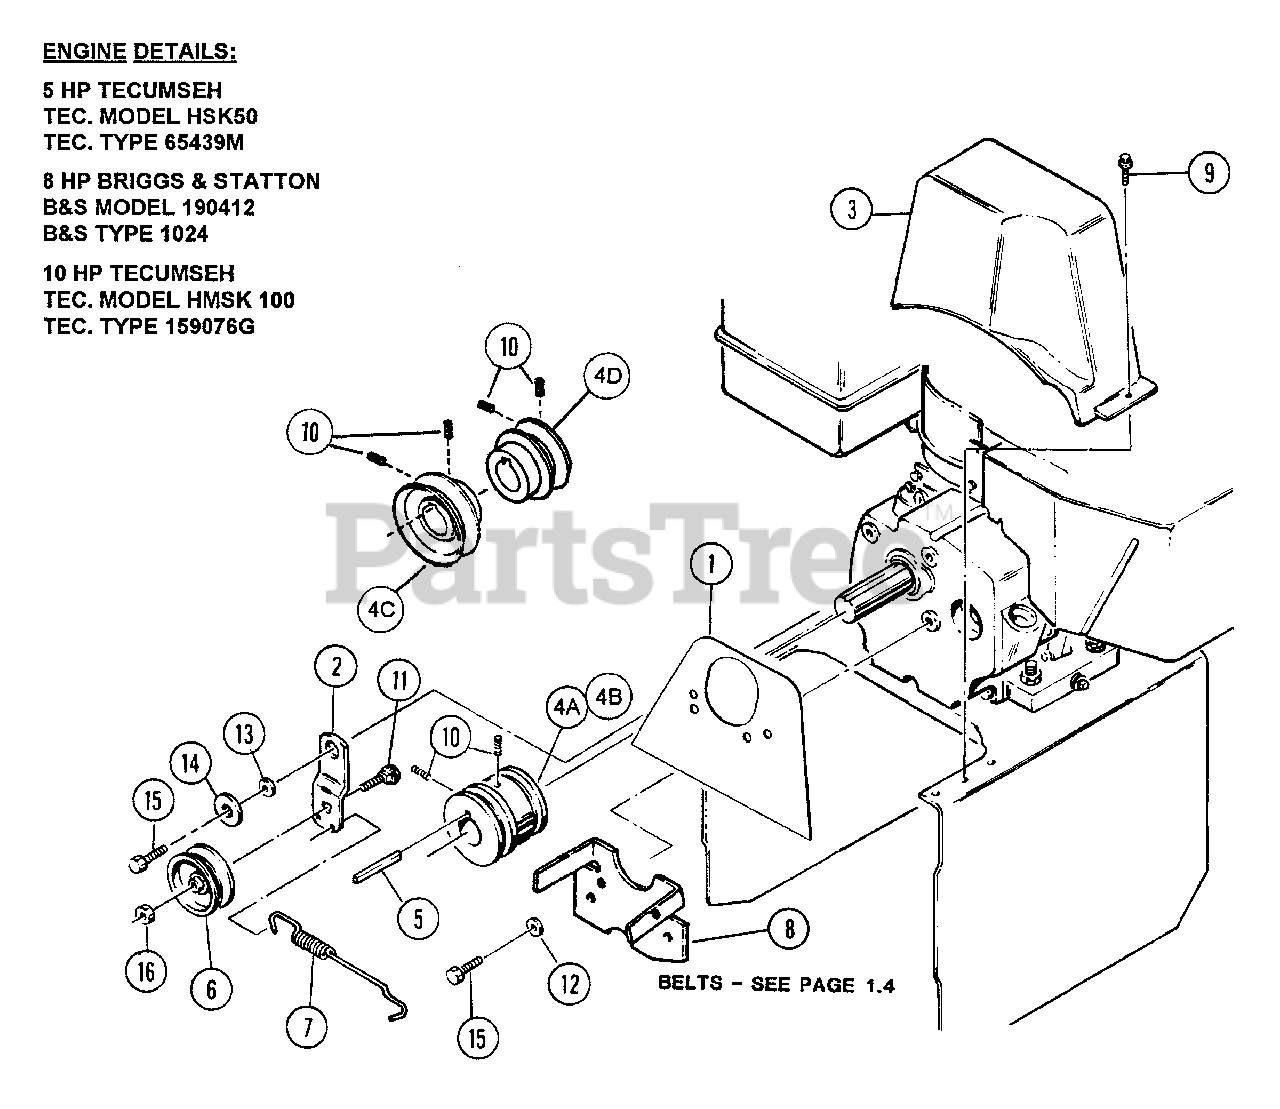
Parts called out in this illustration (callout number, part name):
1	GUARD, Engine
2	ARM, Idler
3	COVER, Belt
4A	PULLEY, Double 1x2.5, 2.75
4B	PULLEY, Double .75x2.5, 2.75
4C	PULLEY, Blower 4L, 2.75
4D	PULLEY, Traction 3L, 2.25
5	KEY, 1/4 Square x 2"
6	IDLER, 2-1/4" Dia.
7	SPRING
8	FINGER, Belt
9	SCREW, 1/4-20 x 3/8" Hex Washer Self-Tap
10	SCREW, 5/16-18 x 5/16" Hex Socket Set
11	BOLT, 3/8-16 x 1-1/2" Square Neck. Carriage, Gr. 2
12	WASHER, 5/16 SAE
13	SPACER
14	WASHER, 3/8" Flat
15	SCREW, 5/16-24 x 5/8" Hex Head Cap, Grade 2
16	NUT, 3/8-16 Hex Top Lock
